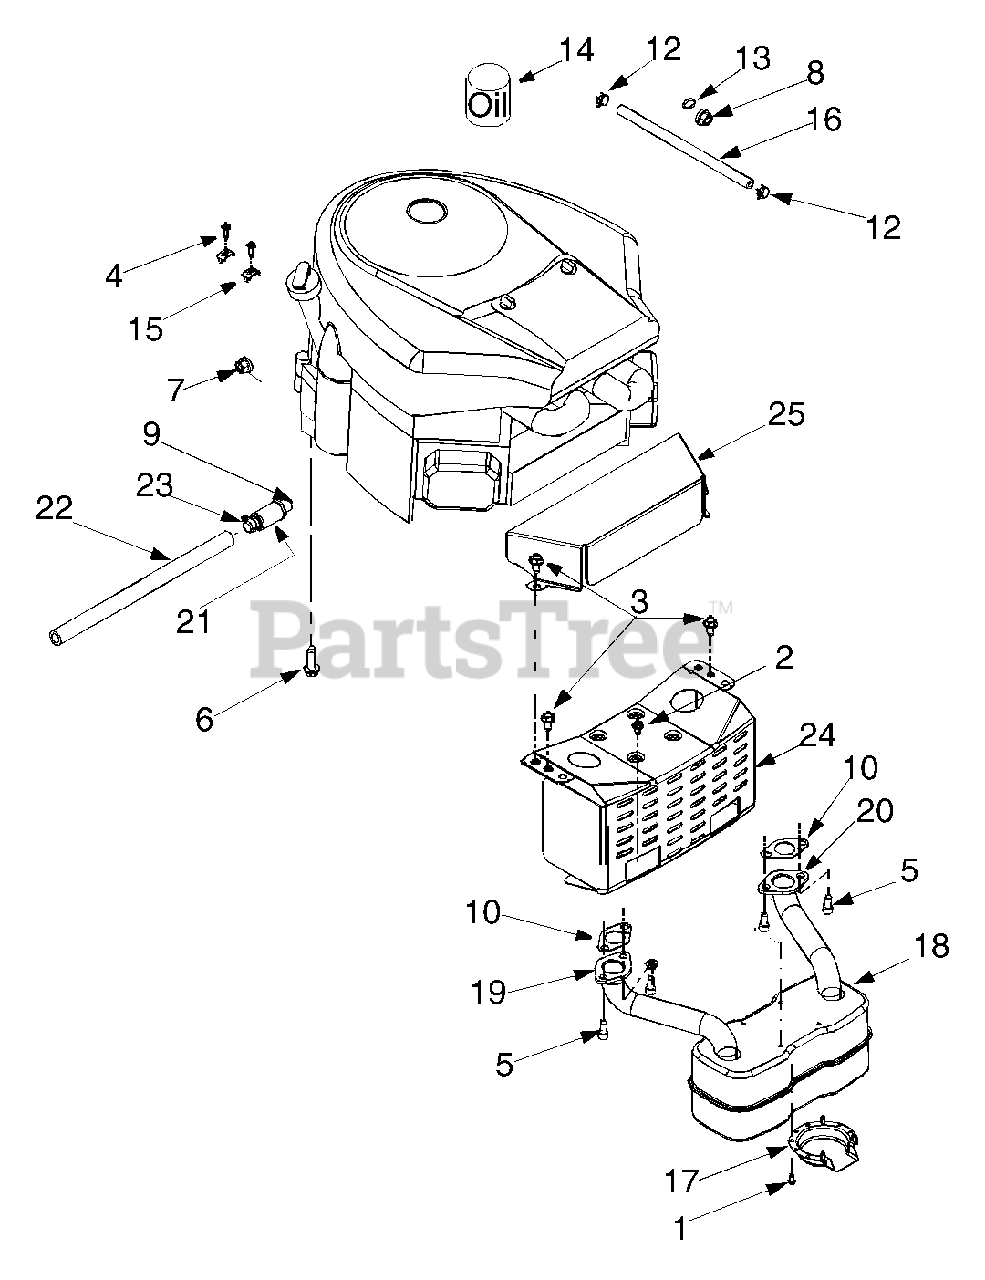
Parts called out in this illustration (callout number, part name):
1	AB Screw 38-18 x 0.5
2	TT Screw 1/4-20 x 0.5
3	AB Screw 5/16-20 x 0.75
4	T Screw #10-32 x 0.625
5	Socket Hd. Scr. 5/16-18 x 0.75
6	TT Screw 3/8-16 x 1.25
9	Pipe Sealant
10	Exhaust Gasket
12	Hose Clamp
13	Flat Washer
14	Oil: SAE 30W
15	Clamp: Casing
16	Fuel Line Hose
17	Deflector: Muffler
18	Dual Inlet Muffler
19	Exhaust Pipe RH
20	Exhaust Pipe LH
21	Oil Drain
22	Oil Drain Extension Hose
23	Oil Drain Cap
25	Heat Shield
